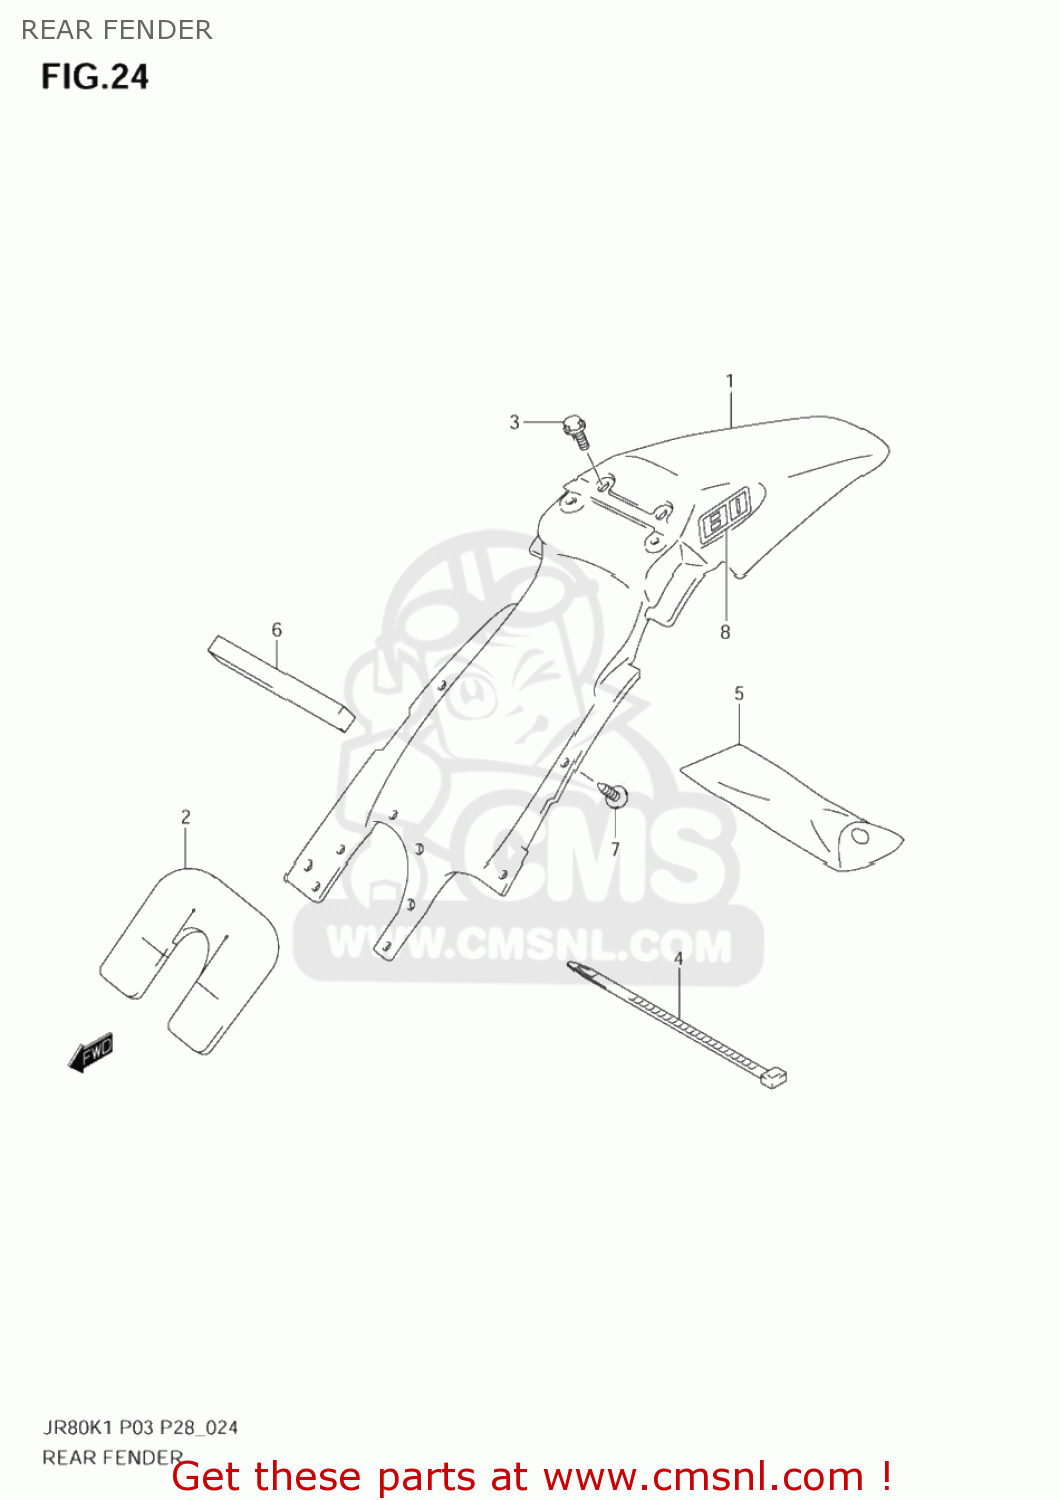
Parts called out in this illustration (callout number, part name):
1	FENDER,RR
2	MUDGUARD,RR FENDER
3	SCREW(6X16)
4	CLAMP(L:250)
5	TOOL ASSY
6	CUSHION,RR FENDER
7	SCREW
8	EMBLEM,RR FENDER
